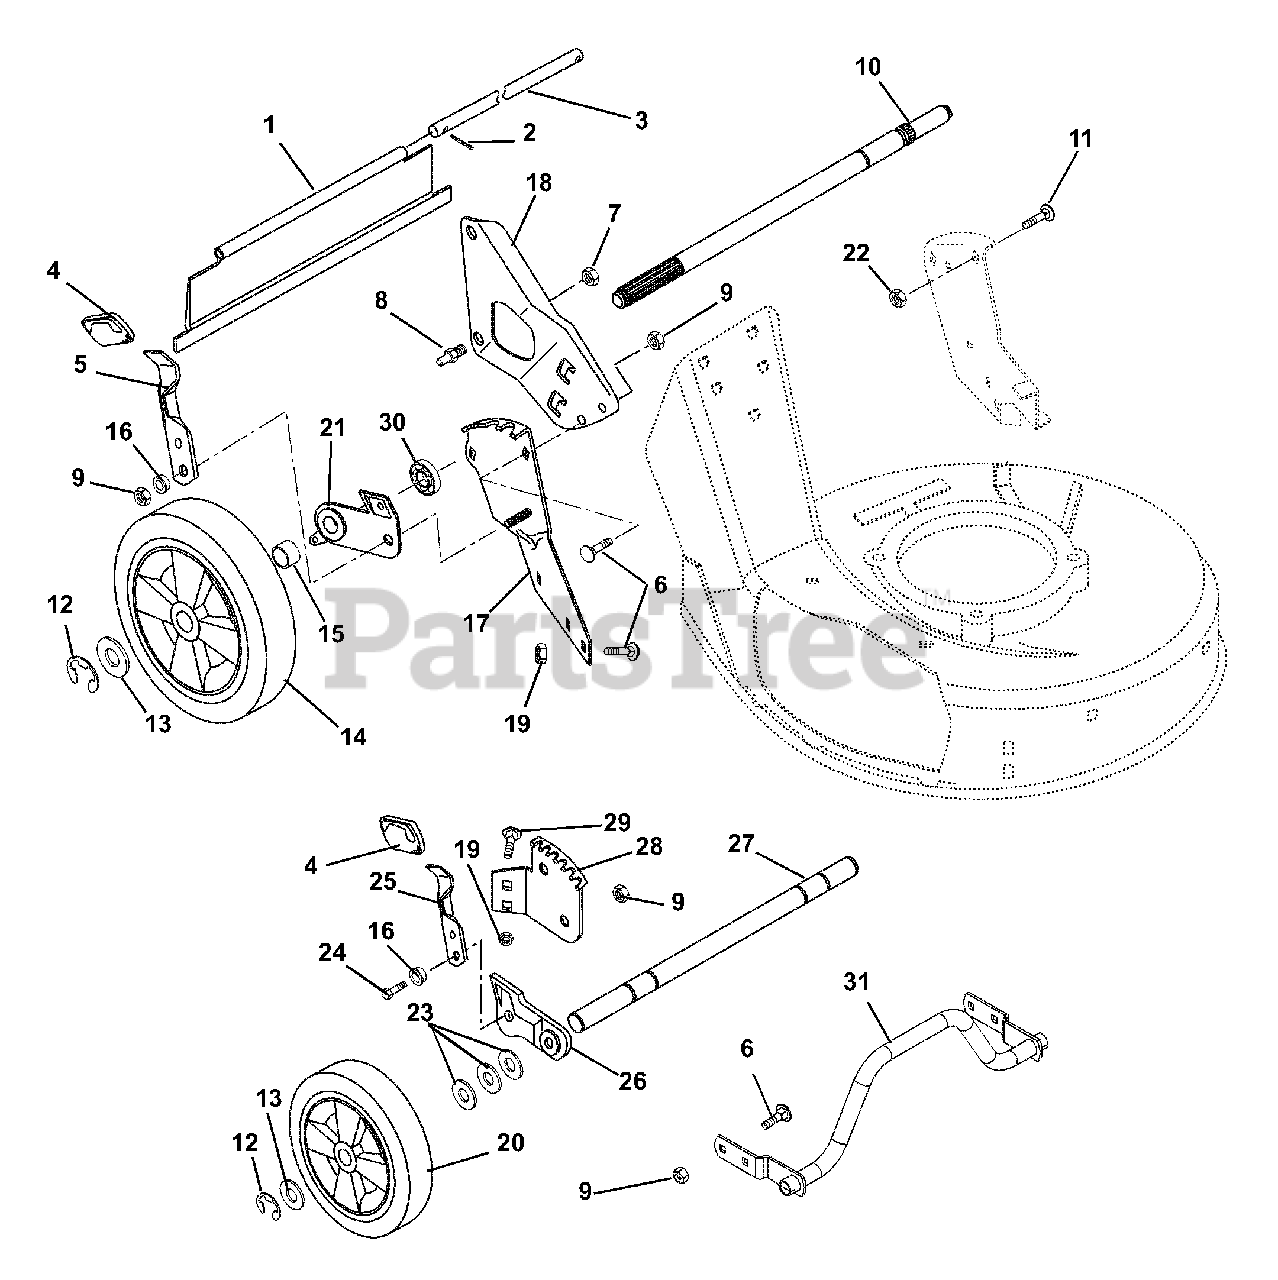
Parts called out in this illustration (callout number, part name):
1	REAR PROTECTIVE GUARD, S.P.
2	@PIN-CTR .06X.50 EXTPRSQCT YWZ
3	ROD
5	LEVER, HEIGHT ADJUSTMENT
6	@BLT-RHDSSQNK .31-18X.62 G5YZ
7	@NUT-LK-CTR .38-16 YWZC
8	HANDLEBAR STUD
9	@NUT-LK-CTR .31-18 YWZC
10	REAR AXLE,5/8 DIA
10	REAR AXLE-PUSH MOWER MM
11	BLT-RDHDSQNK .31-18X1.0 SHTYZ
12	RG-RTNG-EXT .500X.042 (E)
13	WSHR-FL-STL .505X.880X.072 YWZ
14	WHL, LH 10.50"
14	WHL, RH 10.50"
14	10 1/2 TIRE SKIN
14	TIRE, REAR 10X1.75 #6 GRAY
15	SPACER TUBE, SELF PROPEL
16	BSHG-FLG .32X.500X.344X.880
17	QUADRANT, REAR LH
17	QUADRANT, REAR RH
18	RH HANDLEBAR MTG. BRKT
18	LH HANDLEBAR MTG. BRKT
18	RH HANDLEBAR MOUNT WELDMENT
18	LH HANDLEBAR MOUNT WELDMENT
19	@NUT-SPNLK-FLG .312-18 YWZC
20	WHL 7.50" .50 BORE, 1.50 HUB
20	TIRE, FRONT 7X1.50
21	REAR ADJUSTMENT BRACKET L.H.
21	REAR BRACKET & BEARING ASSY RH
21	REAR ADJUSTMENT BRACKET R.H.
22	@NUT-LK-NYL .312-18 YWZC
23	WSHR-FL-STL .52X.827X.062 YWZC
24	@BLT-HEX .31-18X1.00 GR5 YWZC
25	FRONT HEIGHT ADJUSTMENT LEVER
26	LEFT ADJUSTOR BRACKET ASSEMBLY
26	RIGHT ADJUSTOR BRACKET ASSEMBL
27	FRONT AXLE
28	FRONT QUADRANT, LH
28	FRONT QUADRANT, RH
29	@BLT-RDHDSQNK .31-18X.50 G5YZ
30	BRG-BALL .625X1.383X.50
31	GUARD, LM VALVE COVER
